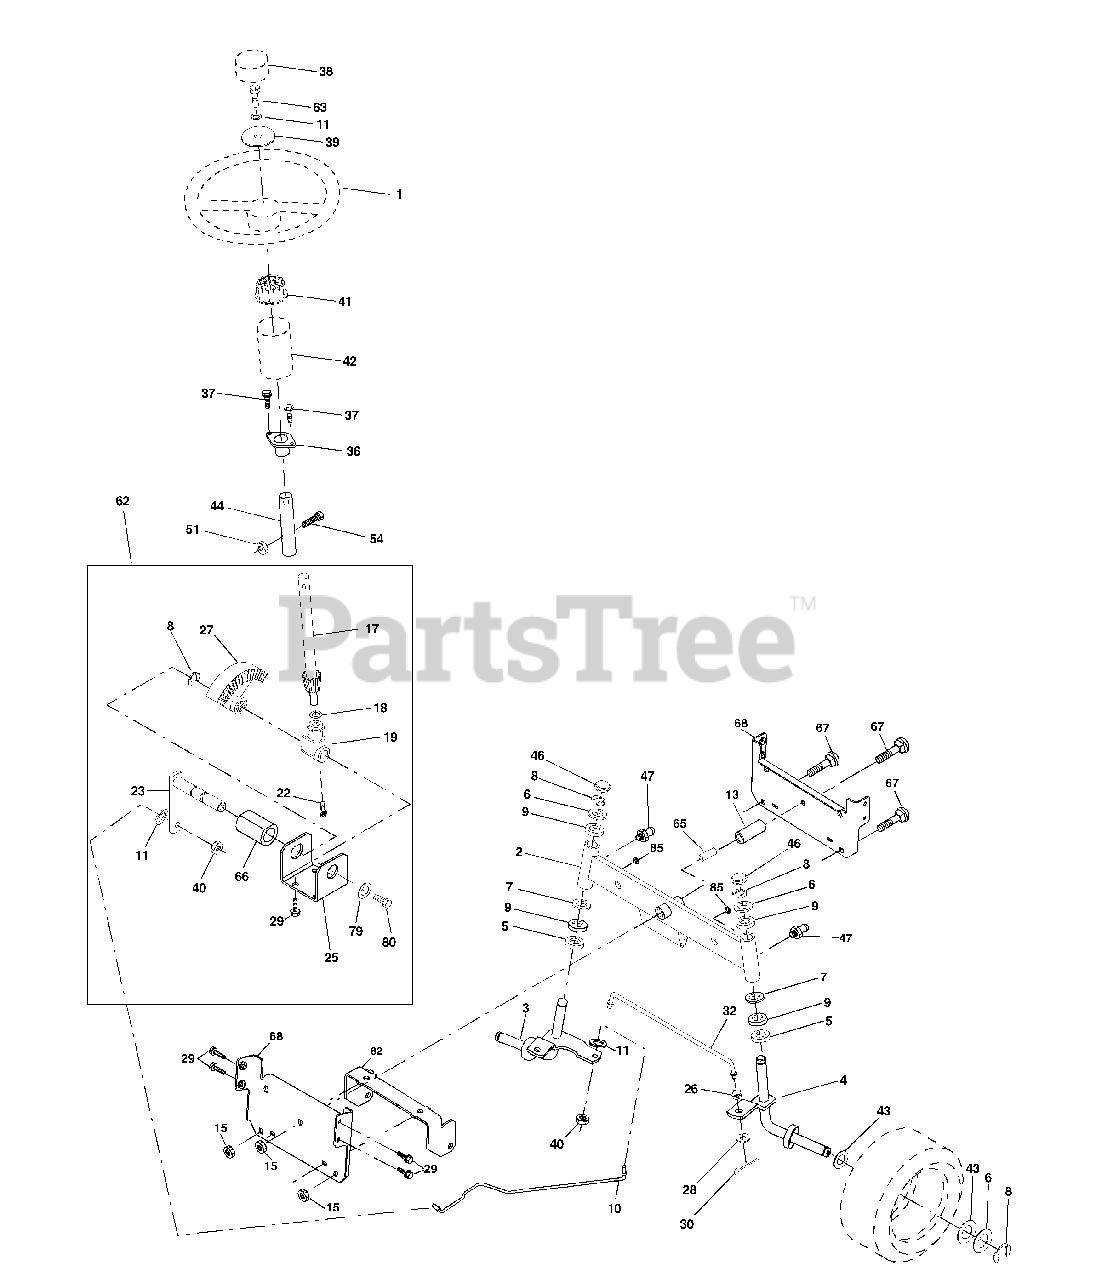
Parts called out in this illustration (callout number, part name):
1	Wheel Steering Auto Black
2	Axle Asm Front
3	Spindle Asm Lh
4	Spindle Asm Rh
5	Bearing Race Thrust Harden
6	Washer 25/32 X 1 5/8 X 16ga
7	Washer 27/32 X 1 1/4 X 16 Ga
8	Ring Klip #t5304-75
9	Bearing Col Strg Blk
10	Link Drag Extended
11	Lockwasher
13	Spacer Bearing Axle Front
15	Hex Flange Lock
17	Shaft Asm Strg 5/8 X 15 19 Lt
18	Washer Thrust 515x 750x 033
19	Support Shaft
22	Screw Hex Wsh Hd Torx
23	Shaft Asm Pittman
25	Bracket Steering
26	Bushing Rod Tie Blk Lt
27	Gear Sector
28	Washer 13/32 X 7/8 X 16ga
29	Screw 3/8-16x3/4
30	Pin
32	Rod Tie Wire Form 19 75 Mech
36	Bushing Strg 5/8 Id Dash
37	Screw TT #10-32 x 5 x 3/8 Flange
38	Insert Cap Strg
39	Washer 13/32 x 2-3/8 x 12Ga
40	Locknut Center
41	Adaptor Wheel Strg 640/ 635id
42	Boot Dash Steering
43	Washer 25/32 X 1 1/4 X 16 Ga
44	Extension Steering Non-Adjust
46	Cap Spindle Fr Top Blk
47	Fitting Grease
51	Nut Lock Hex W/Ins.
54	Bolt Fin Hex 5/16-18 Unc P
62	Kit Steering Assembly Service
63	Bolt Fin Hex 3/8-16unc x Gr. 5
65	Spacer Brace Axle
66	Bearing Arm Pittman
67	Bolt Rdhd Sq 3/8-16 Unc x 2-3/4
68	Brace Axle
79	Washer 13/32 x 1-1/4 x 12 Ga
80	Bolt Hex Nylon 3/8-16 x 3/4
82	Bracket Susp Chassis Front
85	Fastener Christmas Tree
